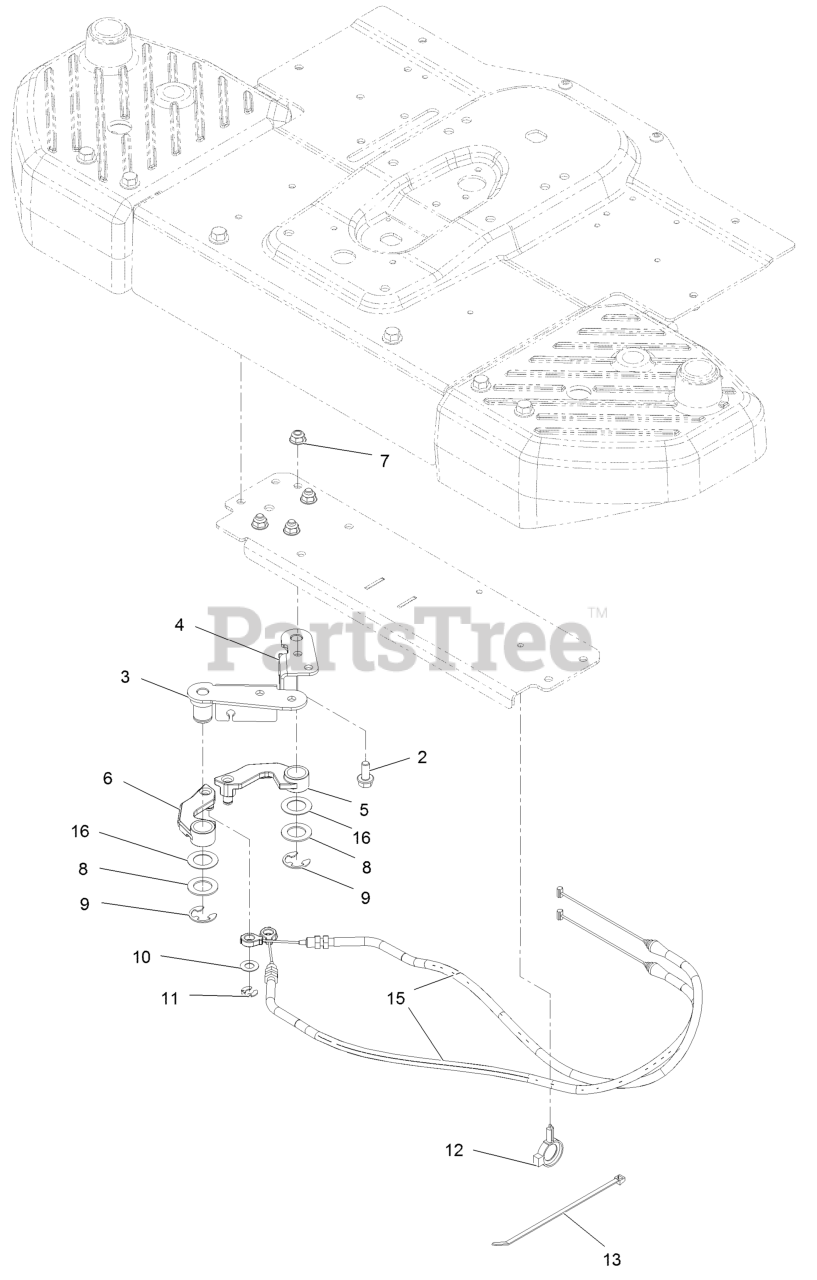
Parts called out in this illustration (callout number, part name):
2	SCREW-HHF
3	CABLE BRACKET ASM
4	CABLE BRACKET ASM
5	ARM-CABLE, RH
6	ARM-CABLE, LH
7	NUT-HF, NI
8	WASHER-THRUST
10	WASHER-THRUST
11	RING-RETAINING
12	CLAMP-HOSE
13	TIE-CABLE
15	CABLE-STEERING
16	WASHER-THRUST
